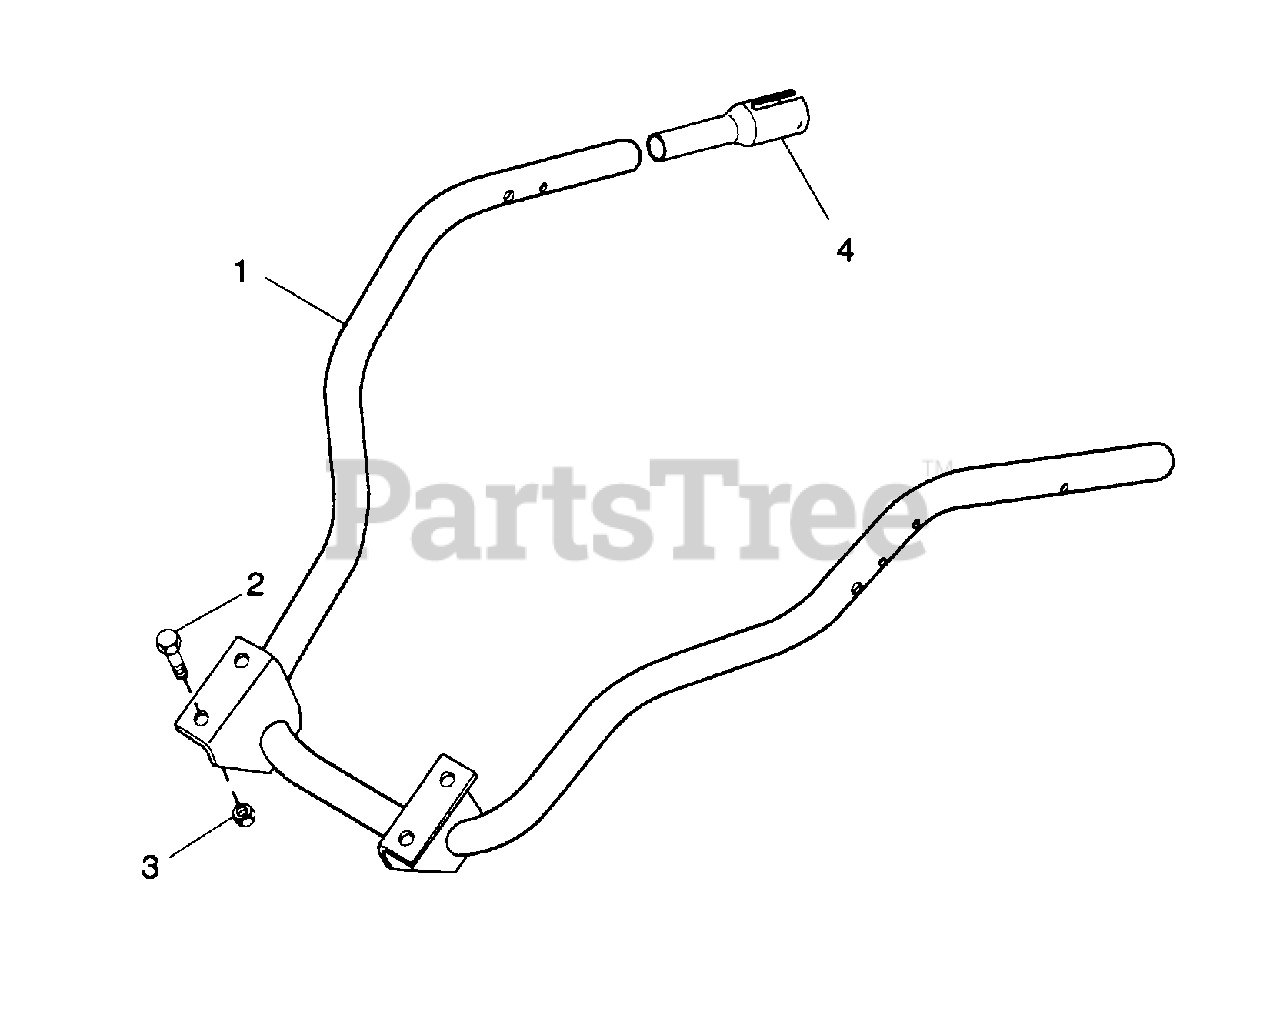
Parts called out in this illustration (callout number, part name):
1	WHL 7.71 X 1.25
2	TIRE 16 X 5W X 3
3	WHL-DISC 6.75 X 9.129
4	NUT-JAM .375-16 PL
5	WSHR-LOCK .375 X .094 MED PL
6	BLT-HEX .38-16 X .625
6	BLT-HEX .38-16 X .75 PL GR 5
7	T/WHL ASSY 8.50-8 X 18
7	T/WHL ASSY 16 X 6.50-8(TURF CHIEF)
7	T/WHL ASSY 4.80/4.00-8 STUD
7	T/WHL 4.80/4.00-8 TRAC R.H.
7	T/WHL 4.80/4.00-8 TRAC L.H.
8	BLT-HEX .50-13 X 1.50 PL GR 5
9	NUT-LK-NYL .50-13 PL
10	HUB, 7" WHEEL
11	HUB, WHEEL
12	BUSH., S1.02 X 1.37 X 1.13 ST
